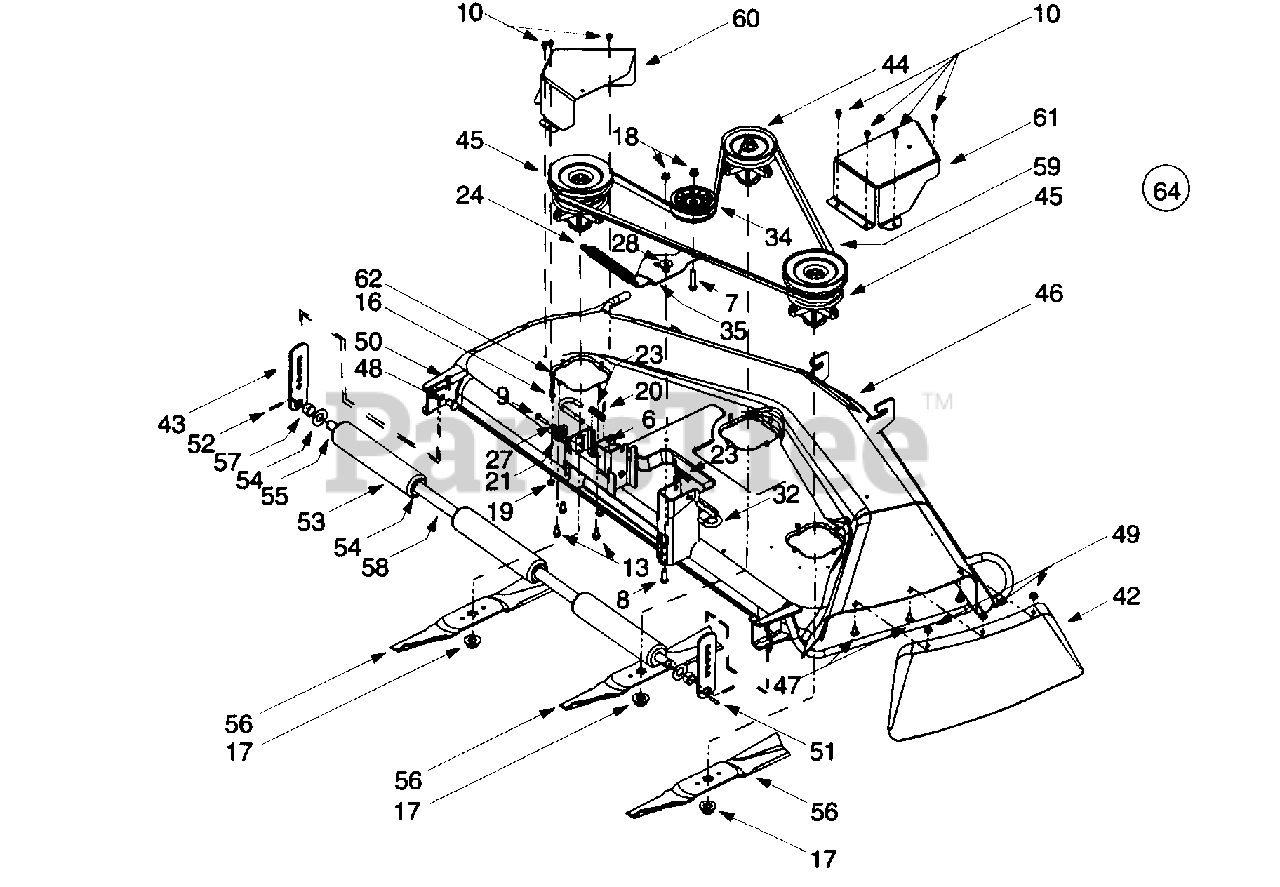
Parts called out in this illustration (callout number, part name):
6	Carriage Screw, 1/4-20 x .5
7	Hex Cap Screw, 3/8-16 x 1.75
8	Hex Cap Screw, 3/8-16 x 1.0
9	Hex Cap Screw, 5/16-18 x 1.25
10	Self Tapping Screw,1/4-20 x .5
13	Self Tapping Screw, 5/16-18 x .75
16	Center Lock Nut, 1/4-20
17	Hex Flange Nut, 5/8-18
18	Flange Lock Nut, 3/8-16
19	Hex Flange Lock Nut, 1/4-20
20	Internal Cotter Pin, .072 x 1.12
21	Deck Adjustment Gear
23	Compression Spring, .406 x .531 x 1.75
24	Extension Spring, .91 x 7.33
27	Lock Washer, 5/16
28	Shoulder Spacer, .625 x .169
32	Deck Release Pin
34	Flat Idler Pulley, 3.5 OD
44	Center Spindle Assembly, 5 Dia.
45	Double Pulley Spindle Assembly
48	Clevis Pin, .50 Dia. x .78
49	Hex Flange Lock Nut, 5/16-18 (Grade 5)
50	Click Pin, .092 x 1.64
51	Spring Pin, 1/4 Dia. x 1
52	Spring Pin, 3/1 6 x 1.25
53	Deck Roller
54	Flat Washer, .78 x 1.59 x .06
55	Deck Roller Shaft, .75 Dia. x 47.12
56	Blade, Star Center, 17.3
57	Spacer, .752 x 1.0 x .53
58	Spacer, .82 x 1.0 x 5.75
59	Deck Belt
